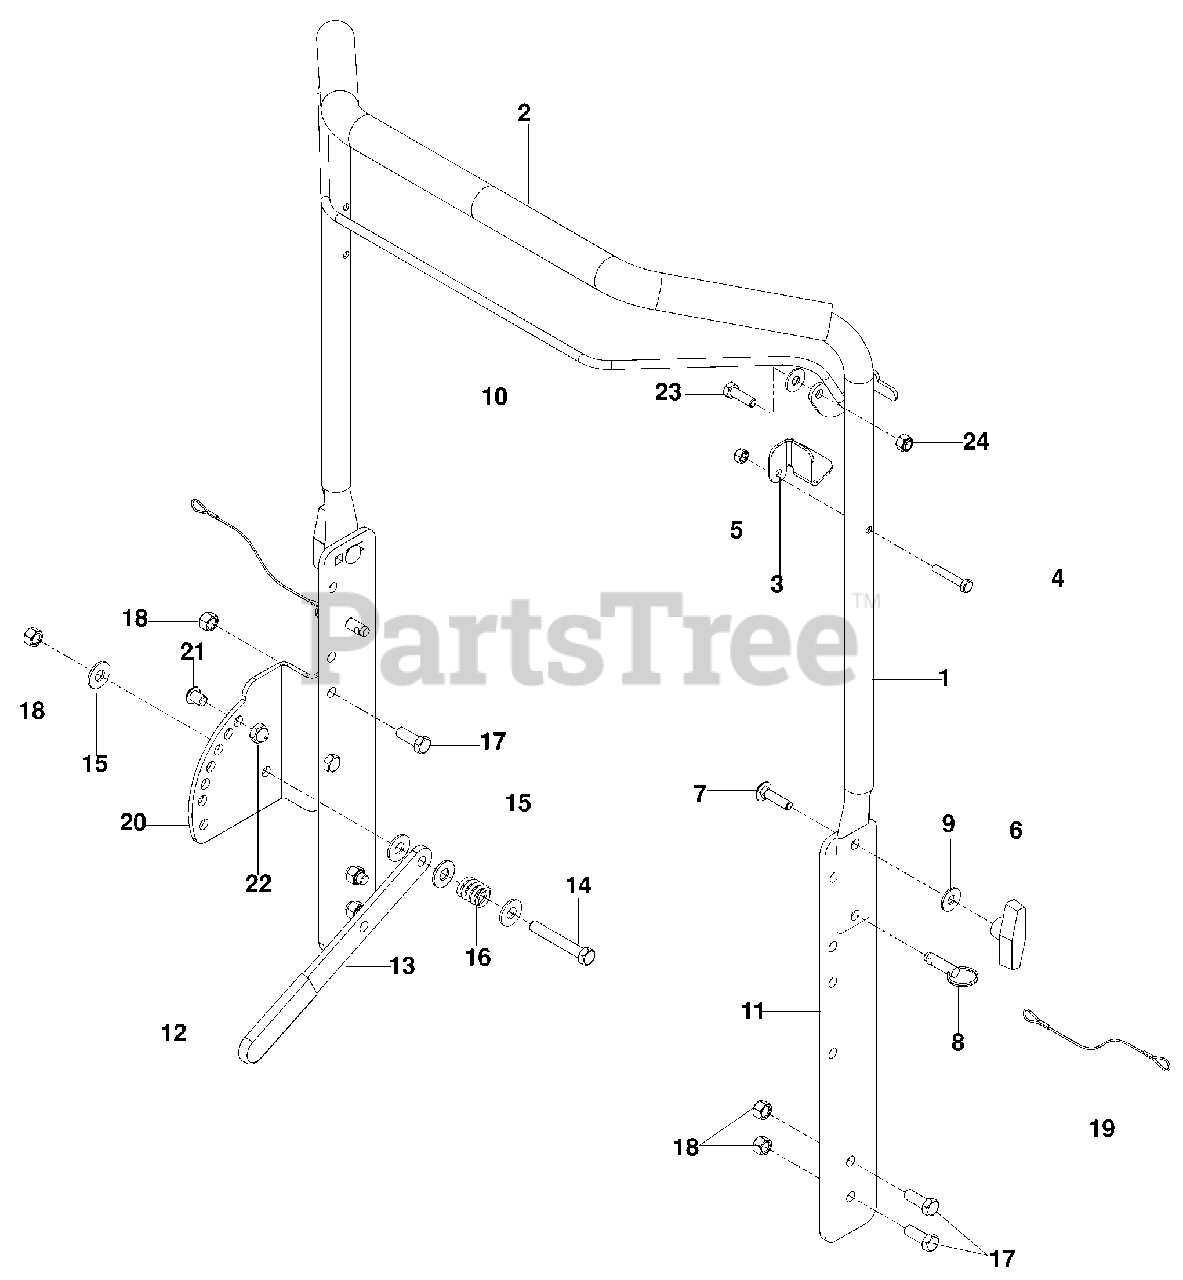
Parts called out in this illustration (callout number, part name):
4	HCS ¼-20 x 1½
5	NUT ¼-20 NYLOC
7	RHSNB 5/16-18 x 1¼
9	WASHER 5/16
11	HANDLE SIDE
12	GRIP, LEVER
14	HCS 3/8-16 x 2½
15	WASHER 3/8
17	HCS 3/8-16 x 1
18	NUT 3/8-16 NYLOC
20	HEIGHT PLATE
21	HCS 3/8-16 x ½ BUTTONHD
22	NUT 3/8-16 ACRON
23	HCS 5/16-18 x 1
24	NUT 5/16-18 NYLOC
